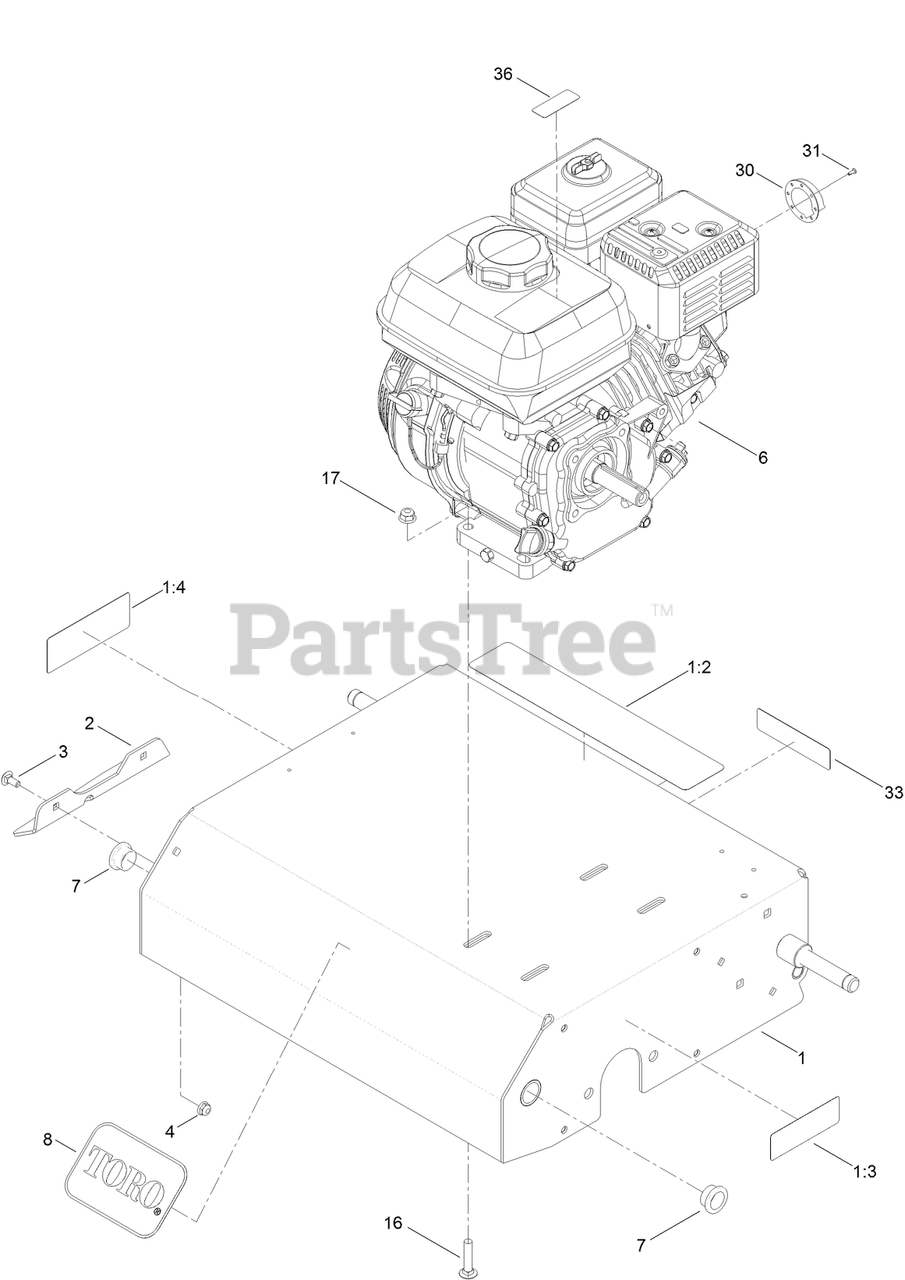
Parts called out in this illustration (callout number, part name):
1	FRAME ASM
1:2	DECAL-WARNING
1:3	DECAL-WARNING, SHIELDS
1:4	DECAL-DANGER
2	GUARD-HAND
3	SCREW-CARR
4	NUT-HF
6	ENGINE-HONDA, GX160
7	BUSHING
8	DECAL
16	BOLT-CARR
17	NUT-HF, NI
30	DEFLECTOR
31	SCREW-PPHTF
33	DECAL-ARRESTER, SPARK
36	DECAL-WARNING, ETHANOL
